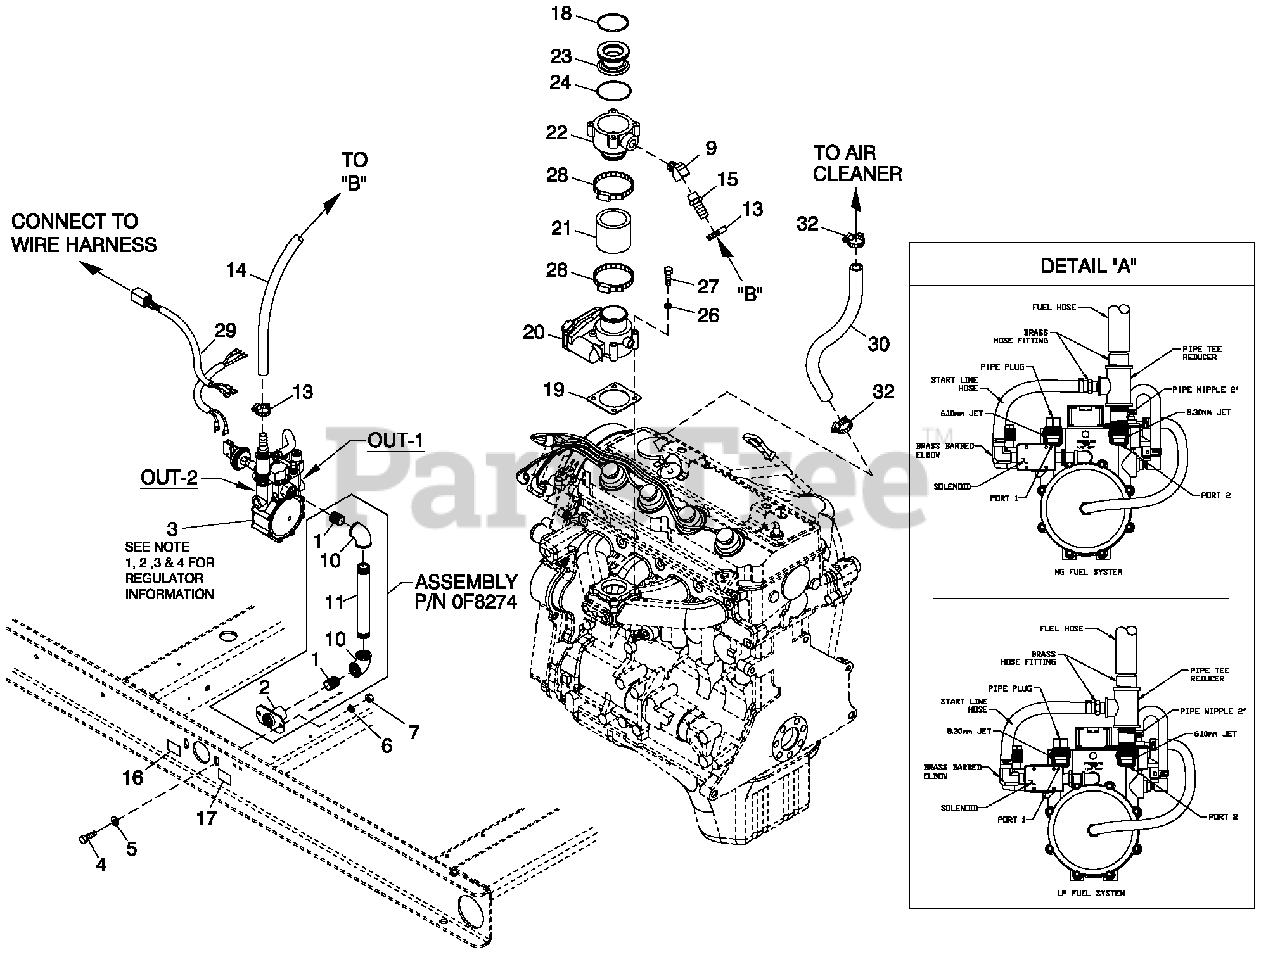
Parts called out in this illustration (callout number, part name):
1	NIPPLE CLOSE 3/4X1.375
2	FLANGElFUELlINLETl
3	REGULATOR ASSY 2.4L (25KW)
4	SCREW HHC M8-1.25X 20 G8.8
5	WASHER FLAT 5/16-M8 ZINC
6	WASHER LOCK M8-5/16
7	NUTlHEXlM8-1.25lG8lCLEARlZINCl
9	STREETlELl45Dl1/2lNPTlBRASSl
10	ELBO l90Dl3/4lNPTl
11	NIPPLElPIPEl3/4lNPTlXl7l
13	CLAMP HOSE #10 .56-1.06
14	HOSE 3/4 ID SAE-30R2 (18" LG)
15	BARBEDlSTRl1/2lNPTlXl3/4l
16	DECALlINLETlPRESSUREl
17	DECALlFUELlINLETlNGl(NATURALlGASlAPPLICATION)
18	O-RINGl45.63lIDlXl2.62l IDTH
19	GASKETlBOSCHl32
20	ACTUATORlBOSCHl40lGOVERNORl(45K )
21	HOSElCOOLl2lINlIDl20R4l(45K )
22	MIXERlACTUATORl32MMlMACHINEDl(25K )
23	VENTURIlTHROTTLEl26MMl(35l&l45K )
24	O-RINGl47.625lIDlXl2.38l IDTHl
26	WASHER LOCK M6-1/4
27	SCREW SHC M6-1.0 X 45 G12.9
28	CLAMPlHOSEl#28l1.32-2.25l
29	HARNESS CPL FUEL JUMPER
30	HOSEl3/8lIDlSINGLElBRAIDl(18"lLG)
32	CLAMPlHOSEl#10l.56-1.06l
